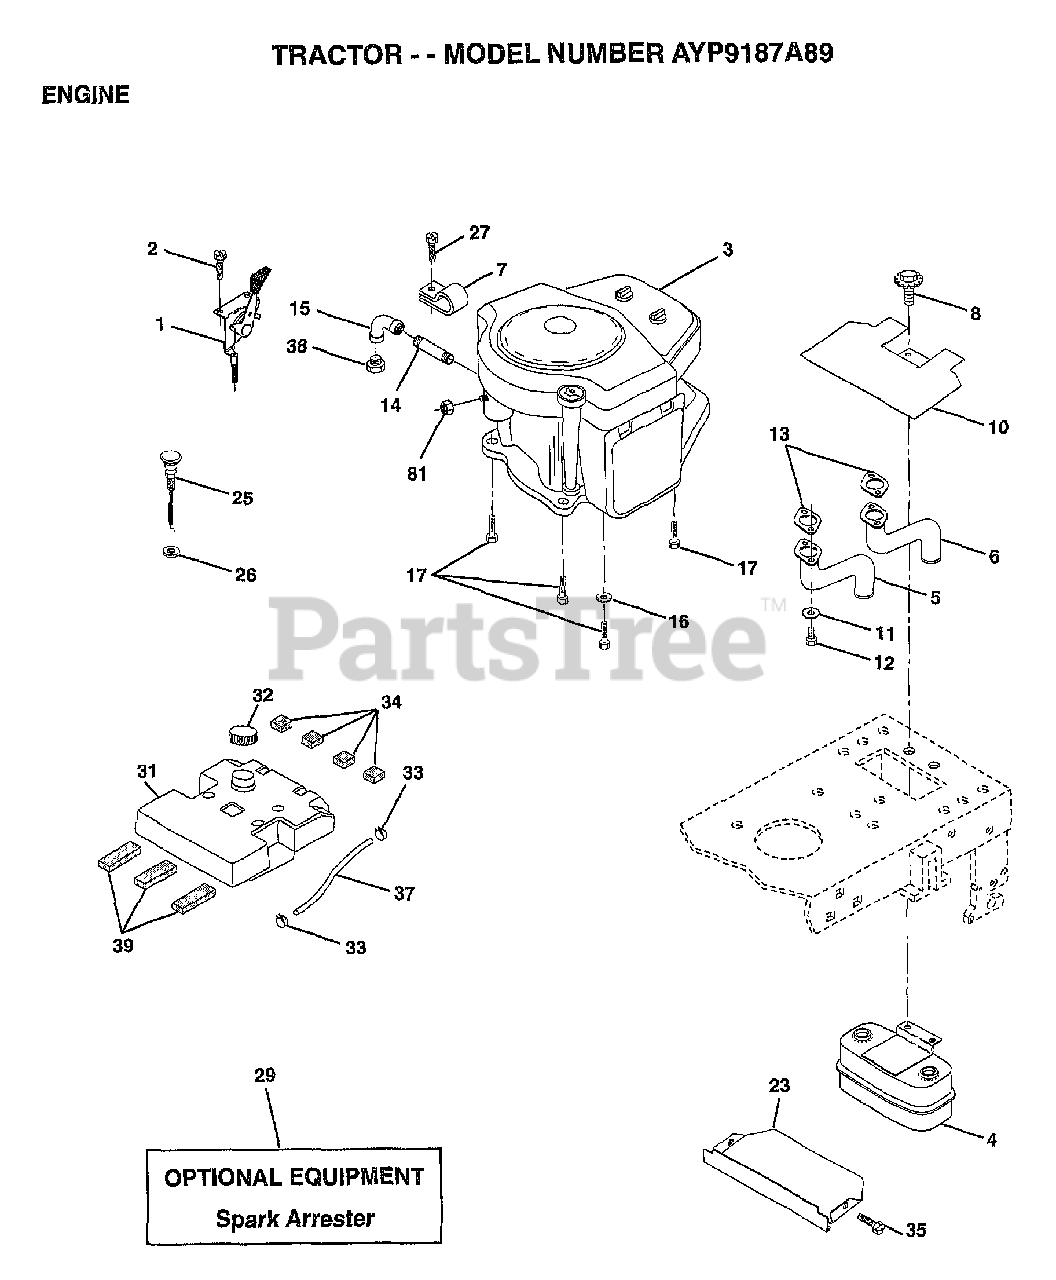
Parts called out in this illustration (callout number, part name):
1	CONTROL THROT 36 LH FLAG
2	SCREW LT
4	MUFFLER.TW.LOTONE
5	TUBE MANIFOLD RH
6	TUBE MANIFOLD LH
7	CLAMP.TUBE.DBL.EN
8	BOLT.5/16-18.UNC
10	SHIELD.HEAT.
11	LOCKWASHER
12	SCREW
13	GASKET MUFFLER
14	PIPE NIPPLE LT
15	ELBOW
16	LOCKWASHER
17	SCREW LT
23	SHIELD.BRN/DBR.GD
25	CONTROL.CHOKE.37
26	"NUT,KEPS 3/8-24IM"
27	"SCREW-TT,10-32 FL"
31	"TANK.FUEL,3.5 GAL"
32	CAP ASM FUEL
33	HOSE CLAMP
34	PAD-SPACER LT
35	SCREW
37	FUEL LINE T
39	PAD IDLER TI
40	BUSHING OUTLET T
41	STEM.TANK.FUEL
81	NUT
